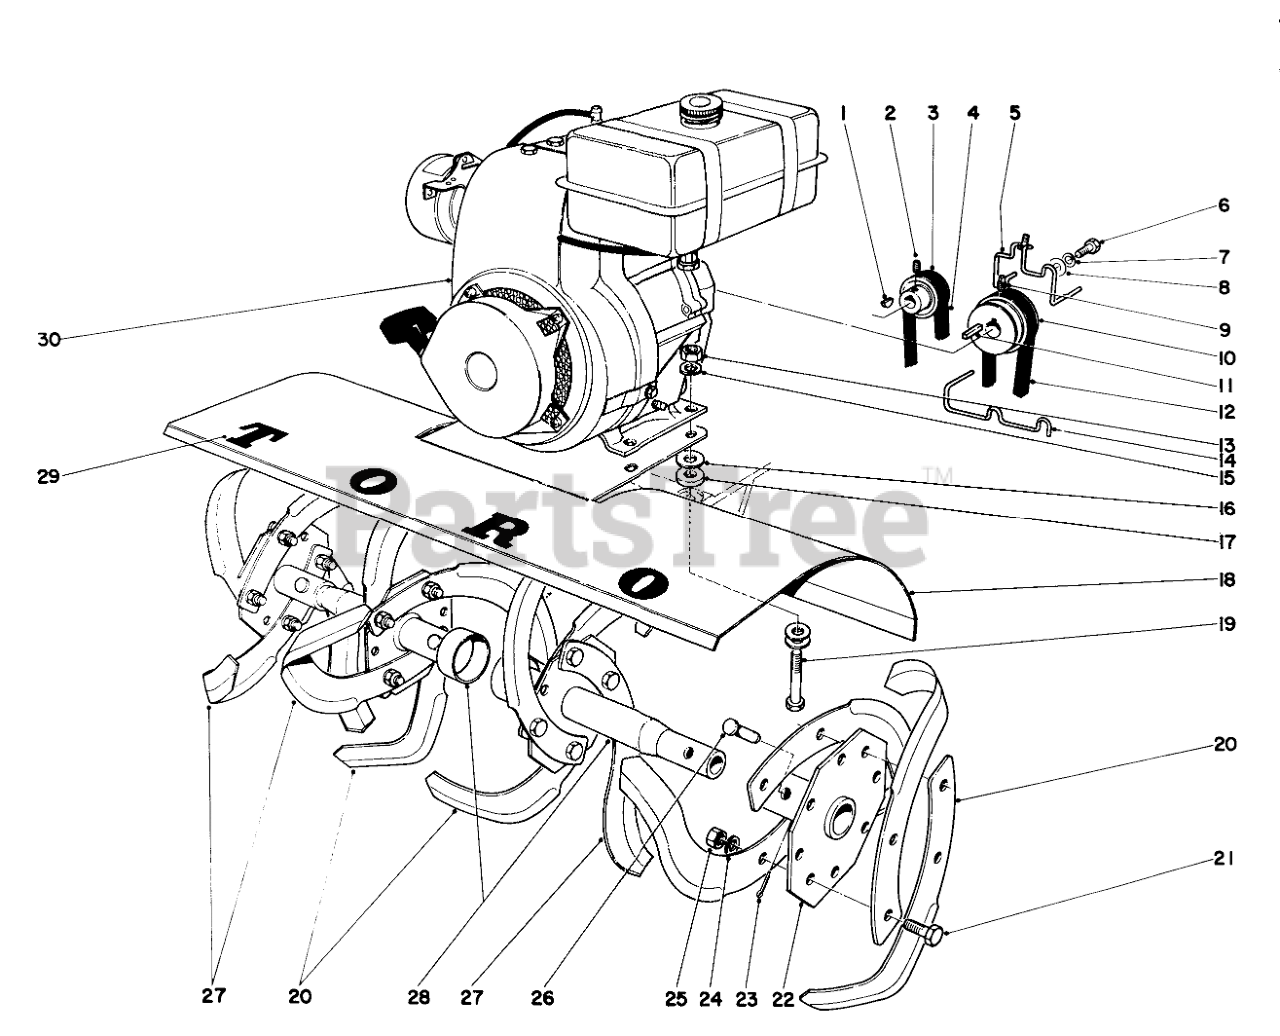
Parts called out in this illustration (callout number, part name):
1	KEY-WOODRUFF
2	SCREW-SET
3	Pulley
5	Belt Guide
6	SCREW-HH
7	WASHER-LOCK
8	WASHER-FLAT
9	SCREW-SET, HSH
10	Engine Pulley
11	KEY-SQUARE
12	Belt
13	NUT-HEX
14	Belt Guide
15	WASHER-LOCK
16	WASHER-FLAT
17	WASHER-FLAT
18	Shield
19	SCREW-HH
20	RH TINE
21	SCREW-HH
22	Axle Hub
23	PIN-COTTER
24	WASHER-LOCK
25	NUT-HEX
26	TINE PIN
27	LH TINE
28	Axle Hub
29	Decal
30	Engine
